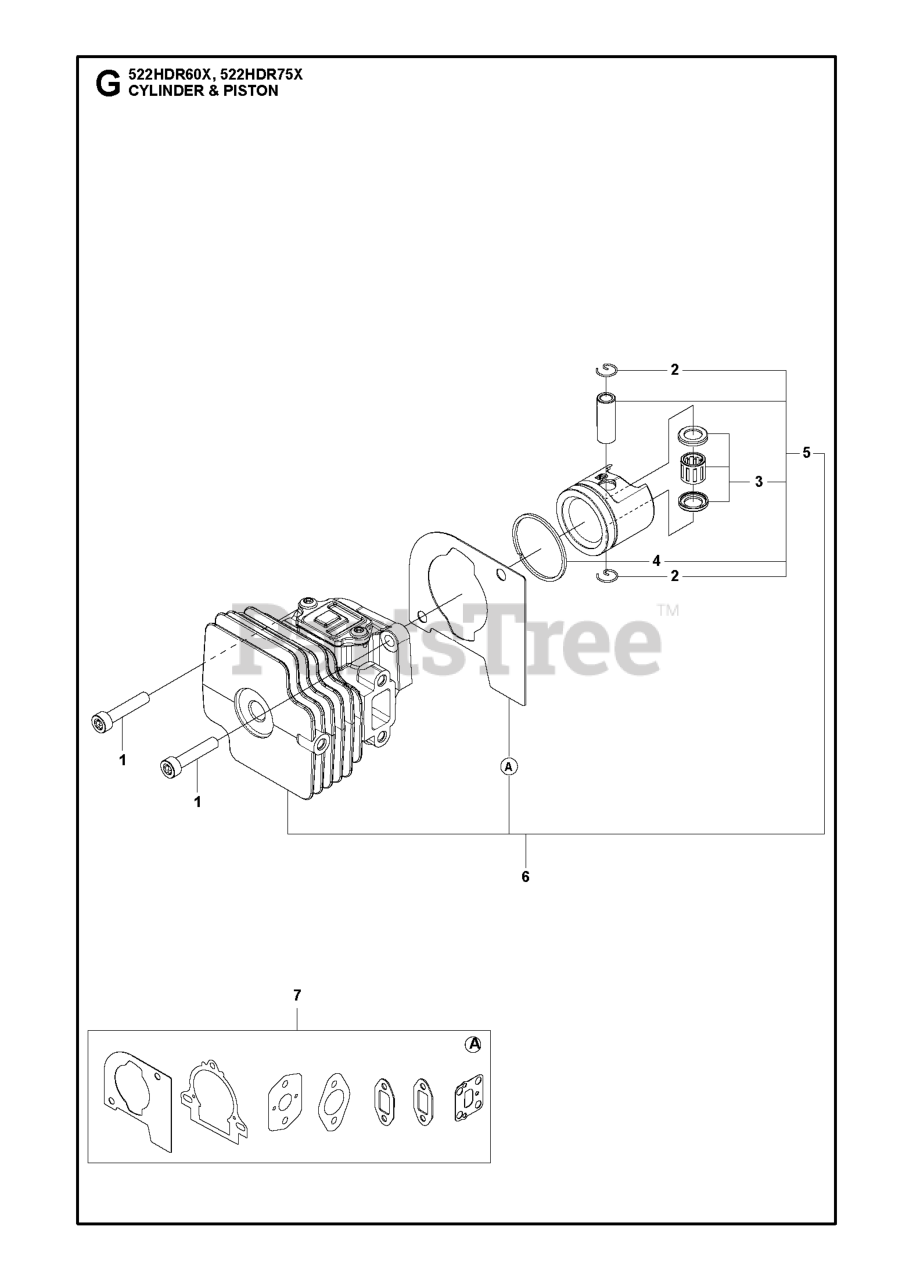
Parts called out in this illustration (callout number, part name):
3	BEARING KIT PISTON PIN
6	CYLINDER ASSY CYLINDER PISTON
7	GASKET KIT 522
